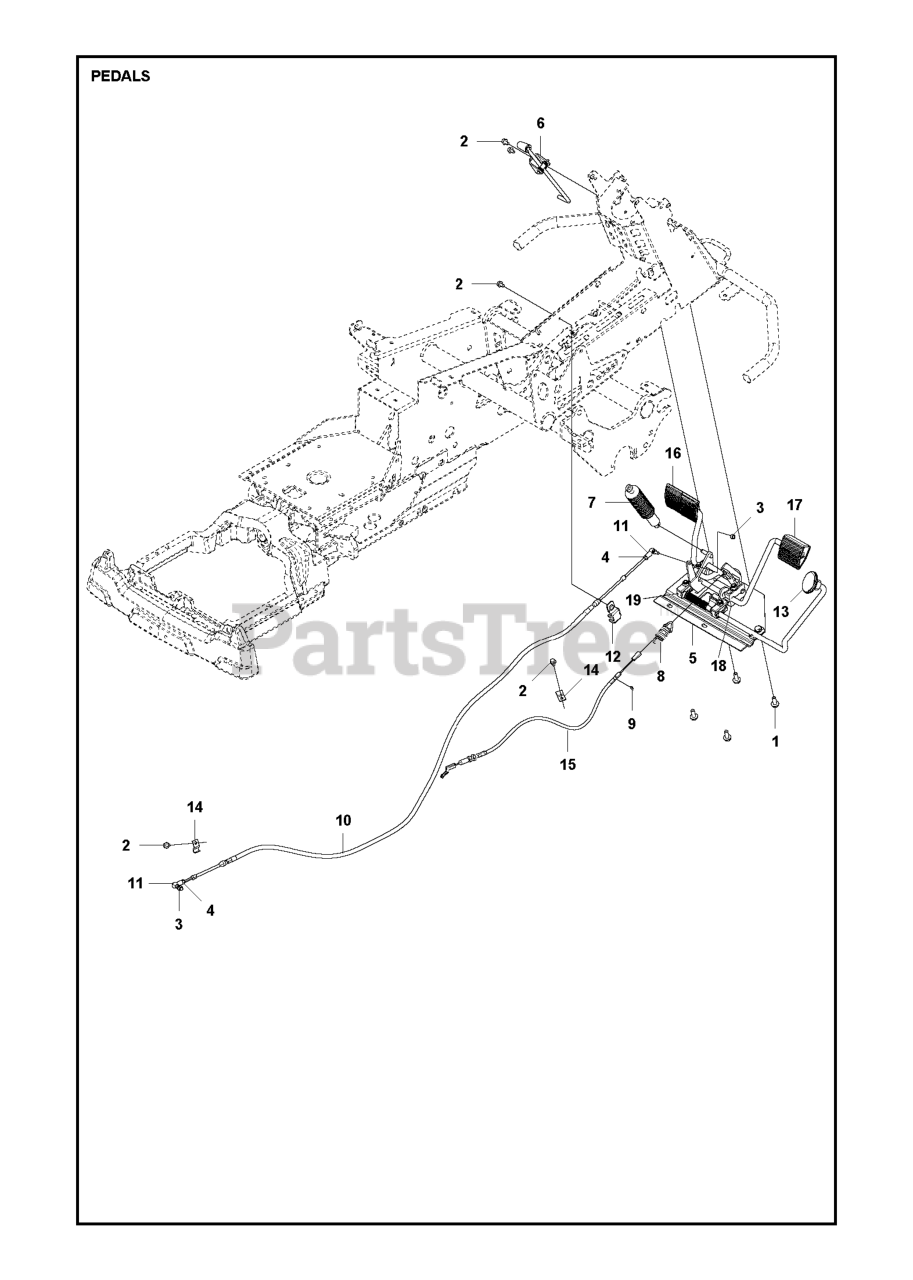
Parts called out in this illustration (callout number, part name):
3	LOCKNUT M6
7	SHOCK ABSORBER
10	CONTROL CABLE TRANSMISSION
11	CONNECTOR, BALL JOINT
13	KNOB, THREADED
16	PEDAL RUBBER L = 102MM
17	PEDAL RUBBER
18	PEDAL SHAFT CLAMP
